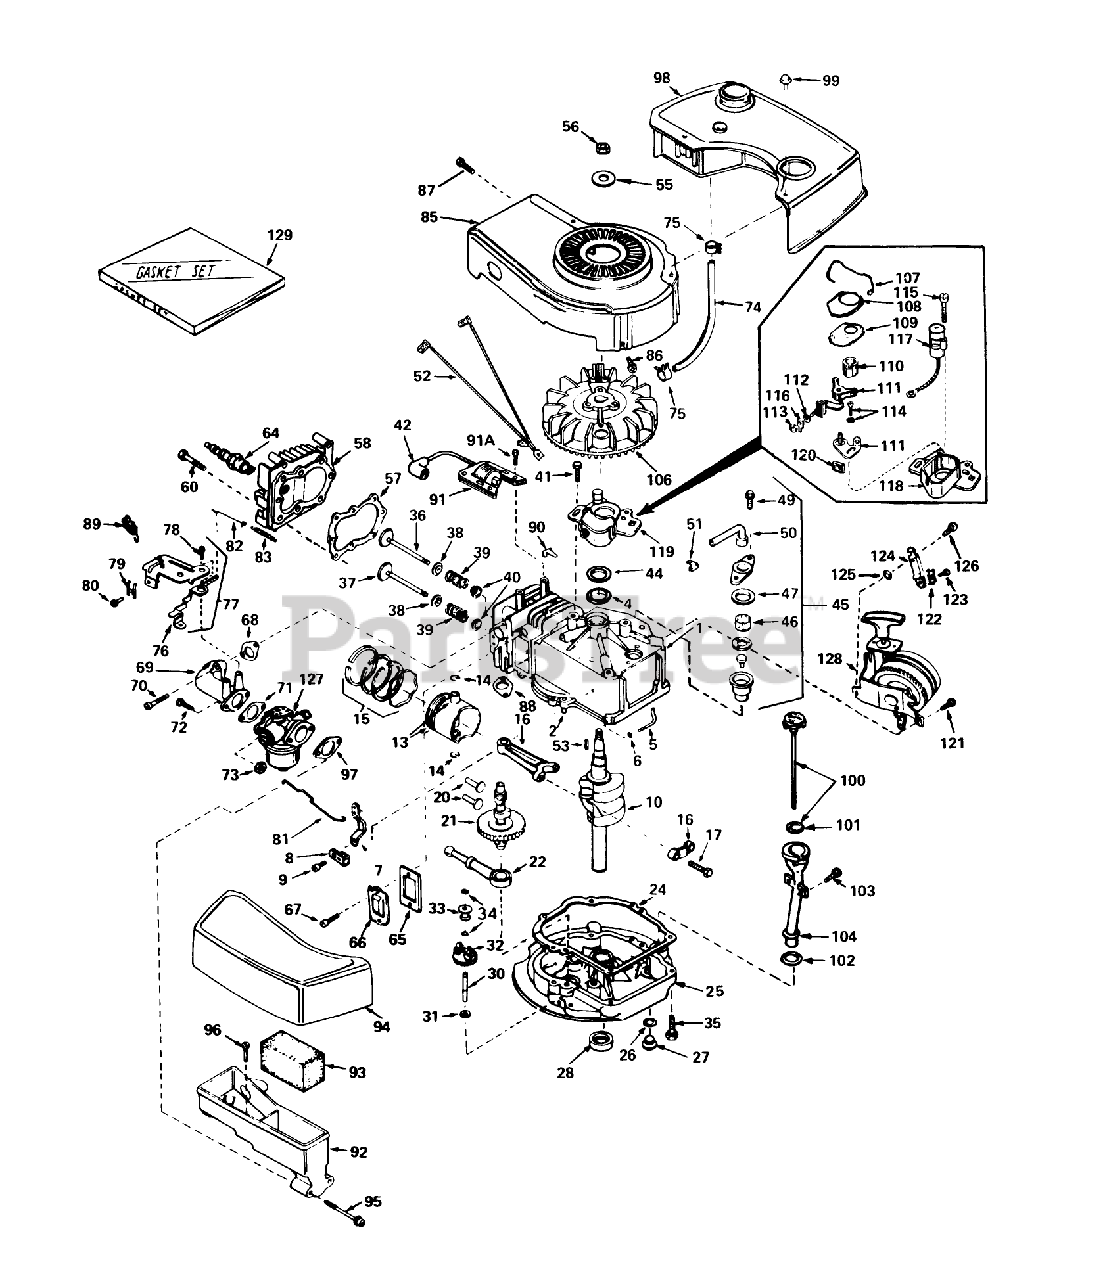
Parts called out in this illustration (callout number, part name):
1	Cyiinder Assy. (Incl. Ref. #2, 4 105)
2	Pin-Dowel
4	Seal-Oil
5	Rod, Governor (Incl. No. 36)
6	Washer-Flat
7	Governor Lever
8	Clamp-Lever, Governor
9	Screw
10	Crankshaft
13	Piston, Pin Ring Assy. (Incl.Ref. #14 15)(Std.)
13	Piston, Pin Ring Assy. (Incl. #14 15)(.010 oversize)
13	Piston, Pin Ring Assy. (Incl.Ref. #14 15) (.020 oversize)
14	Ring-Retaining, Piston Pin
15	Ring Set Piston (Std.)
15	Ring Set Piston (.010 Oversize)
15	Ring Set Piston (.020 Oversize)
16	Rod Assy., Connecting (Incl. Ref. #17)
17	Bolt-Rod, Connecting
20	Lifter-Valve
21	Camshaft(Mech.Comp. Release)
22	Oil Pump ASM
24	Gasket, Mounting
25	Flange Assy., Mounting (Incl. Ref. #26thru 30)
26	Gasket-Oil Drain
27	Plug Oil Drain
28	Seal Oil
30	Shaft-Governor
31	Washer-Flat
32	Governor Gear ASM
33	Spool-Governor
34	Ring-Retaining
35	Screw (1/4-20 x 1-1/4)
36	Valve, Intake (Incl. Ref. #38, 39 40) (Std.)
36	Valve, Exhaust (1/32" Oversize) (Incl. Nos. 8, 9 10)
37	Valve, Exhaust (Standard) (Incl. Nos. 8, 9 10)
37	Valve, Exhaust (1/32" Oversize) (Incl. Nos. 8, 9 10)
38	Cap-Upper Valve Spring
39	Spring-Valve
40	Cap-Valve, Spring
41	Screw
42	Cover-Spark Plug
44	Gasket Stator
45	Breather Assy. (Incl. Ref. #46, 47, 49, 50 51 )
46	Element-Breather
47	Gasket-Breather
49	Screw, Hex Hd. w/Conical
50	Tube, Breaker
51	Clip, Breather
52	Wire Ground
53	682488 LB GRASS HI-
55	Washer-Belleville
56	Nut-Flywheel
57	63573 GIL 42 SNWTHW
58	Head-Cylinder
60	Screw (5/16-18x1-1/2)
64	Plug, Spark (J17LM or equiv.)
64	Plug, Spark (Champion RCJ-8)
65	Gasket-Breather
66	Cover-Valve
67	Screw
68	Gasket, Intake
69	Pipe, Intake
70	Screw (1/4-20 x 1)
71	Gasket-Carburetor
73	Nut and Lock Washer (1/4-28)
74	Line-Fuel
75	Clamp-Line, Fuel
76	Lever Control
77	Control Assy., Speed (Incl. Nos, 76, 78 89)
78	Screw, Hex Washer Hd Shoulder Self-Tap
79	Conduit
80	Screw (10-32 x 3/8)
81	Link-Throttle
82	Link Governor Spring
83	Spring Governor
85	Housing Blower
86	Screw
87	Screw (10-24 x 9/16)
88	Gasket Exhaust
89	Terminal
90	Clip-Wire
91	Lamination Coil Assy. (Incl. No. 42)
91A	Screw
92	Body Air Cleaner
93	Filer, Air
94	Cove, Air Cleaner
95	Screw Fil Hd.
96	Screw, Hex Hd.
97	Gasket-Air Cleaner
98	Tank, Fuel
99	Screw (10-32 x 35/64)
100	Dipstick, Oil (Incl. Ref. #101)(Twist Lock)
101	O-Ring
102	Gasket
103	Screw (10-32 x 1/2)
104	Tube-Oil Fill
106	FIywheel
107	Spring Breaker Box
108	Cover-Dust
109	Gasket-Dust Cover
110	Cam-Breaker
111	Breaker Assy.
112	Washer
113	DECAL
114	Breaker Screw
115	Condenser Screw
116	Terminal, Ground
117	Condenser
118	Stator Plate
119	Stator Plate Assy. (incl. Nos. 107, 111 thru 118 120)
120	Felt,Cam Wiper
121	Screw (1/4-20 x 1/2)
122	Conduit
123	Screw (10-32 x 3/8)
124	Bracker
125	Washer
126	Screw (1/4-20 X 5/8)
127	Carburetor (Incl. Ref. #71 )
128	Starter
129	53024/VAR.16HP O/P
